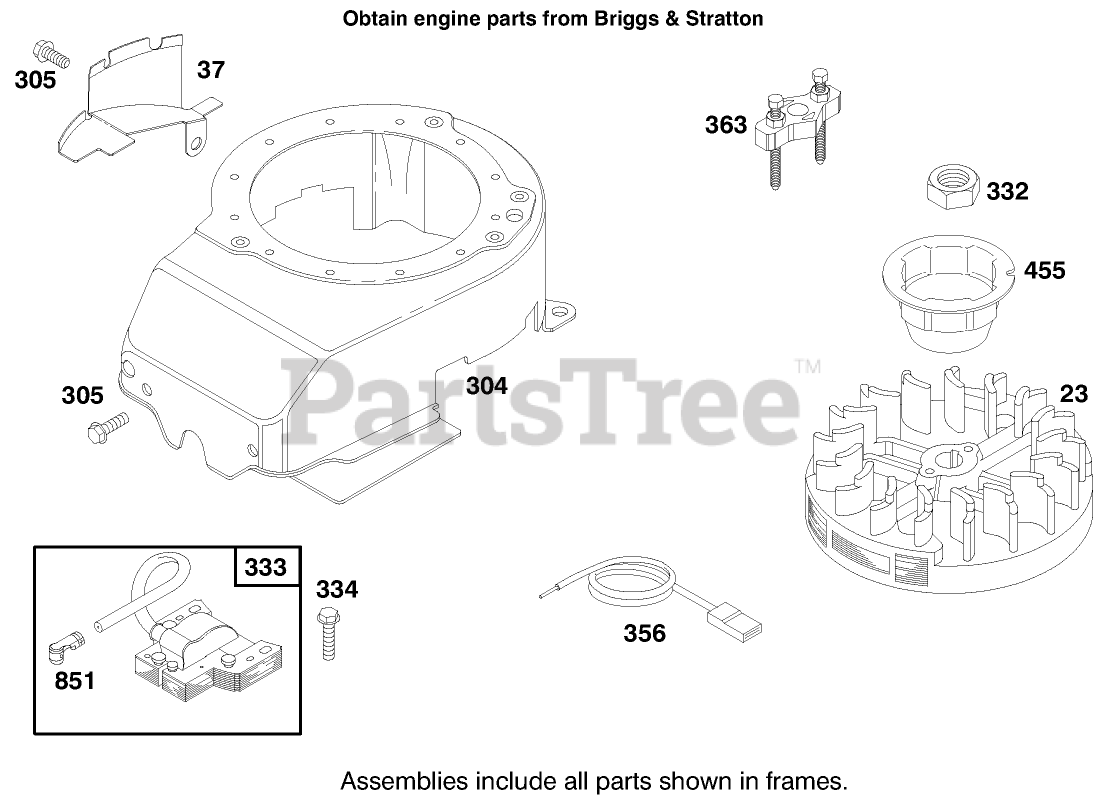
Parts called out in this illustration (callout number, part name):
23	Flywheel
37	Flywheel Guard
304	Housing-Blower
305	Screw-Hex
333	Armature-Magneto
334	Screw-Sem
356	Wire Stop
363	Puller-Flywheel
851	Terminal-Spark Plug
